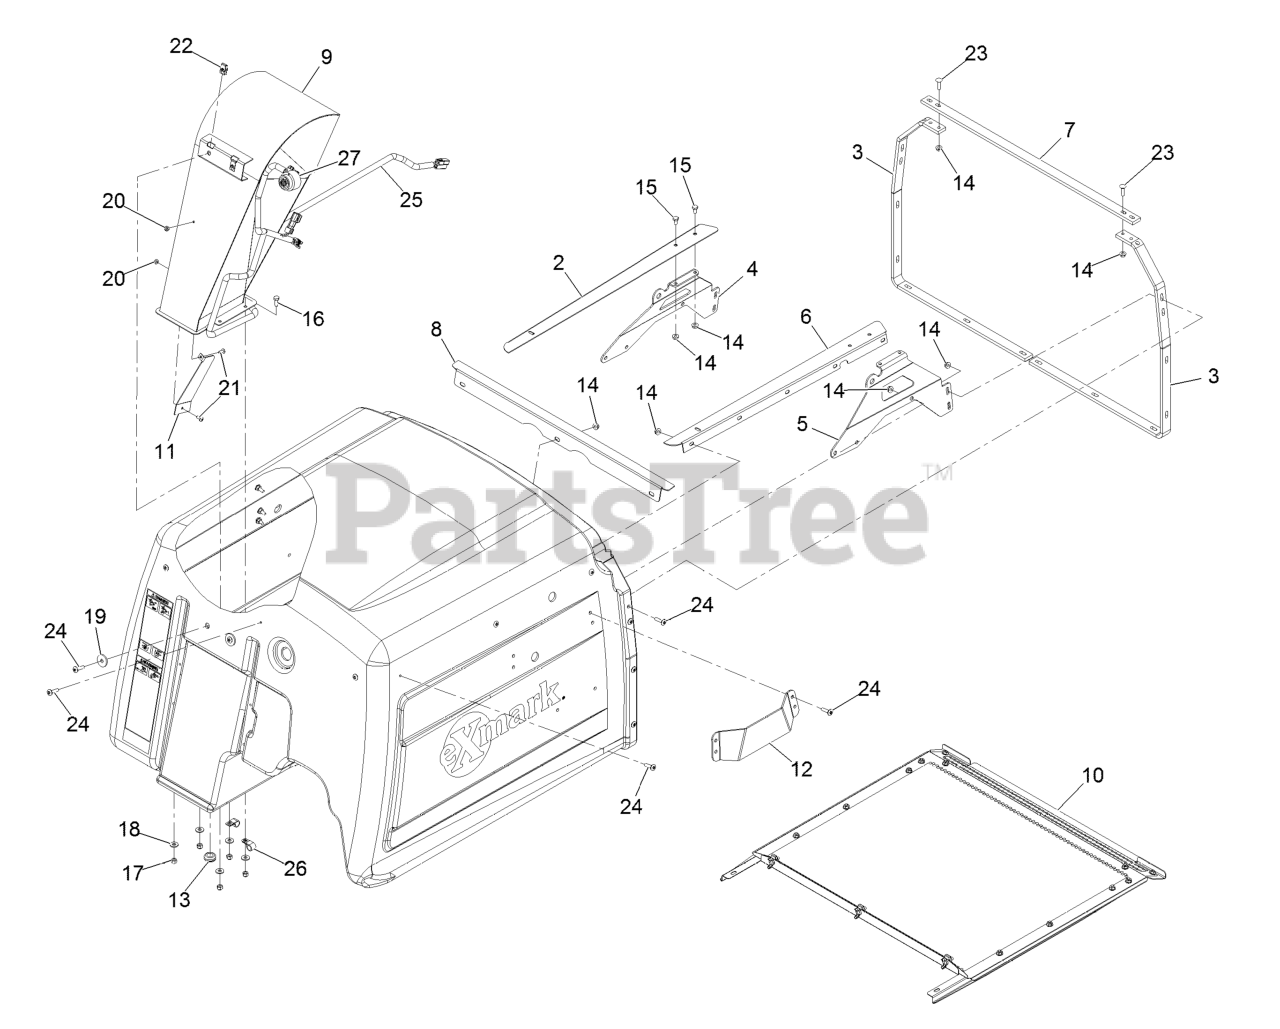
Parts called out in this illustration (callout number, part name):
2	ANGLE-SCREEN TRACK, RH
3	REINFORCEMENT-HOPPER
4	BRACE-DOOR PIVOT, RH
5	BRACE-DOOR PIVOT, LH
6	ANGLE-SCREEN TRACK, LH
7	BRACKET-FRAME CONNECT
8	CHANNEL-SCREEN, FRONT
10	HOPPER SCREEN ASM
11	DEFLECTOR-DISCHARGE CHUTE
12	PLATE-GUARD
13	GROMMET
15	SCREW-HH
16	SCREW-HH
17	NUT-LOCK, NI
18	WASHER-FLAT
20	NUT-LOCK, NI
21	SCREW-PTH
22	Nut-Retainer-Panel 1/4-20
23	SCREW-CARR
24	SCREW-TTH
25	HARNESS-WIRE, HOPPER
26	CLIP-LOOM
27	ALARM-TONE, DUAL
